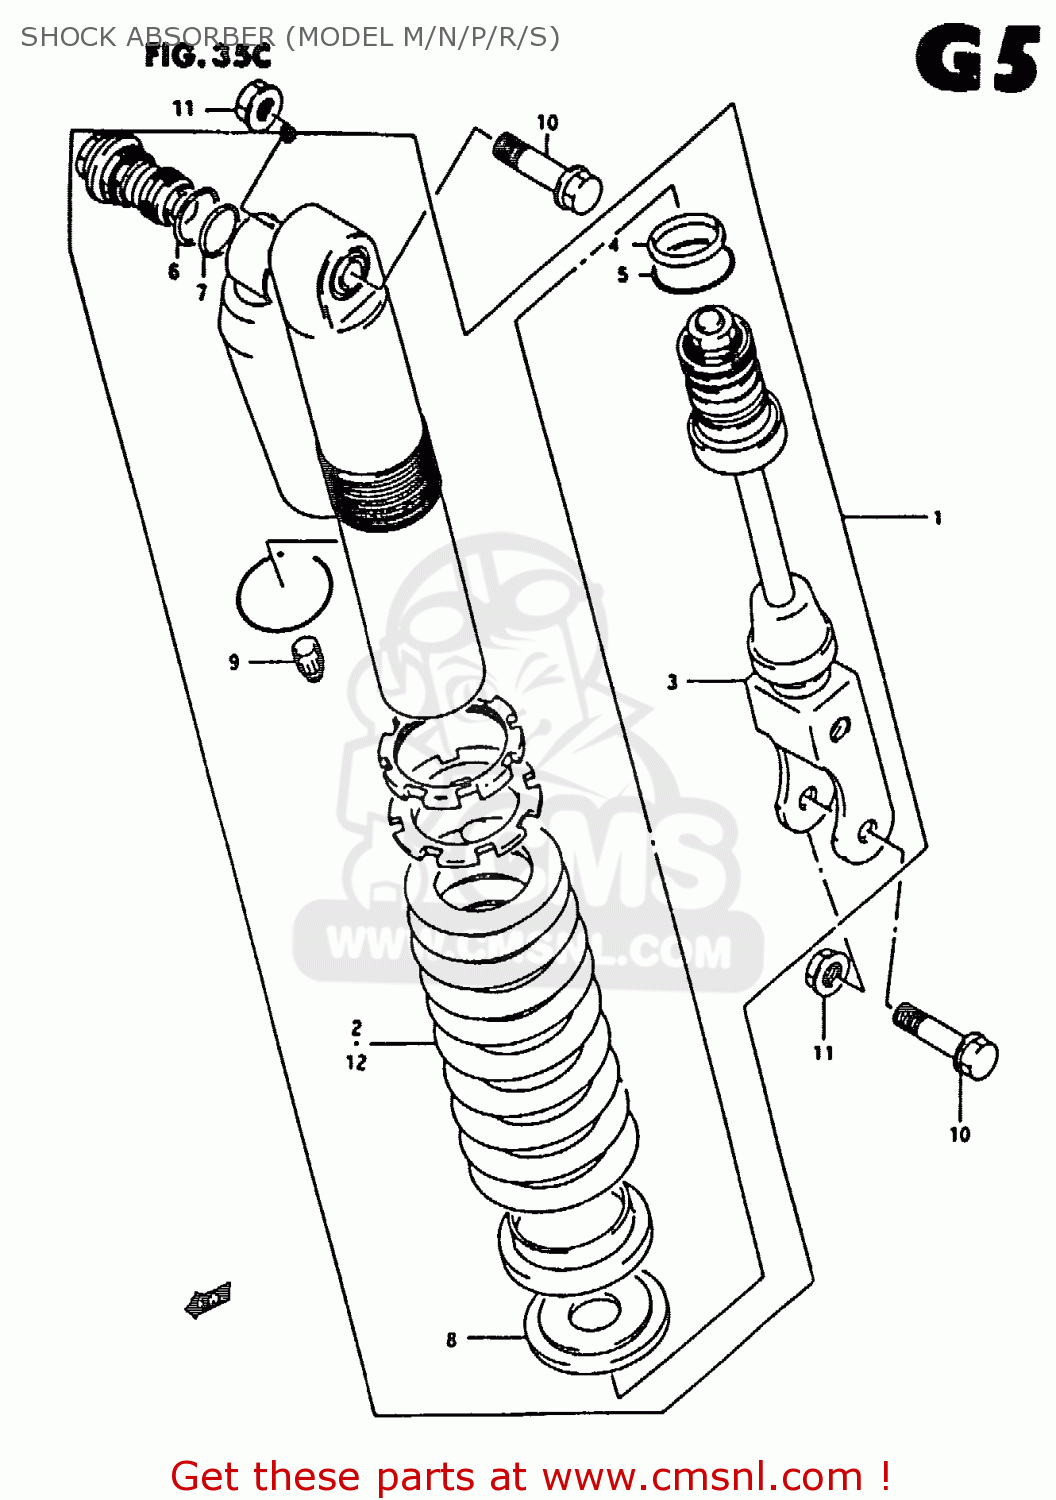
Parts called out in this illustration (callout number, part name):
1	ABSORBER ASSEMBLY,REAR SHOCK
2	SPRING
3	ROD,PISTON
4	O RING
5	RING,PISTON ROD STOPPER
6	O RING
7	O RING
8	SEAT,SPRING STOPPER
9	CAP
10	BOLT,RR CUSHION ROD UPR
11	NUT
12	SPRING(SOFT)
14	CUSHION,REAR SHOCK ABSORBER
15	CLAMP
16	SPRING (HARD)
17	SPRING (HARD)
